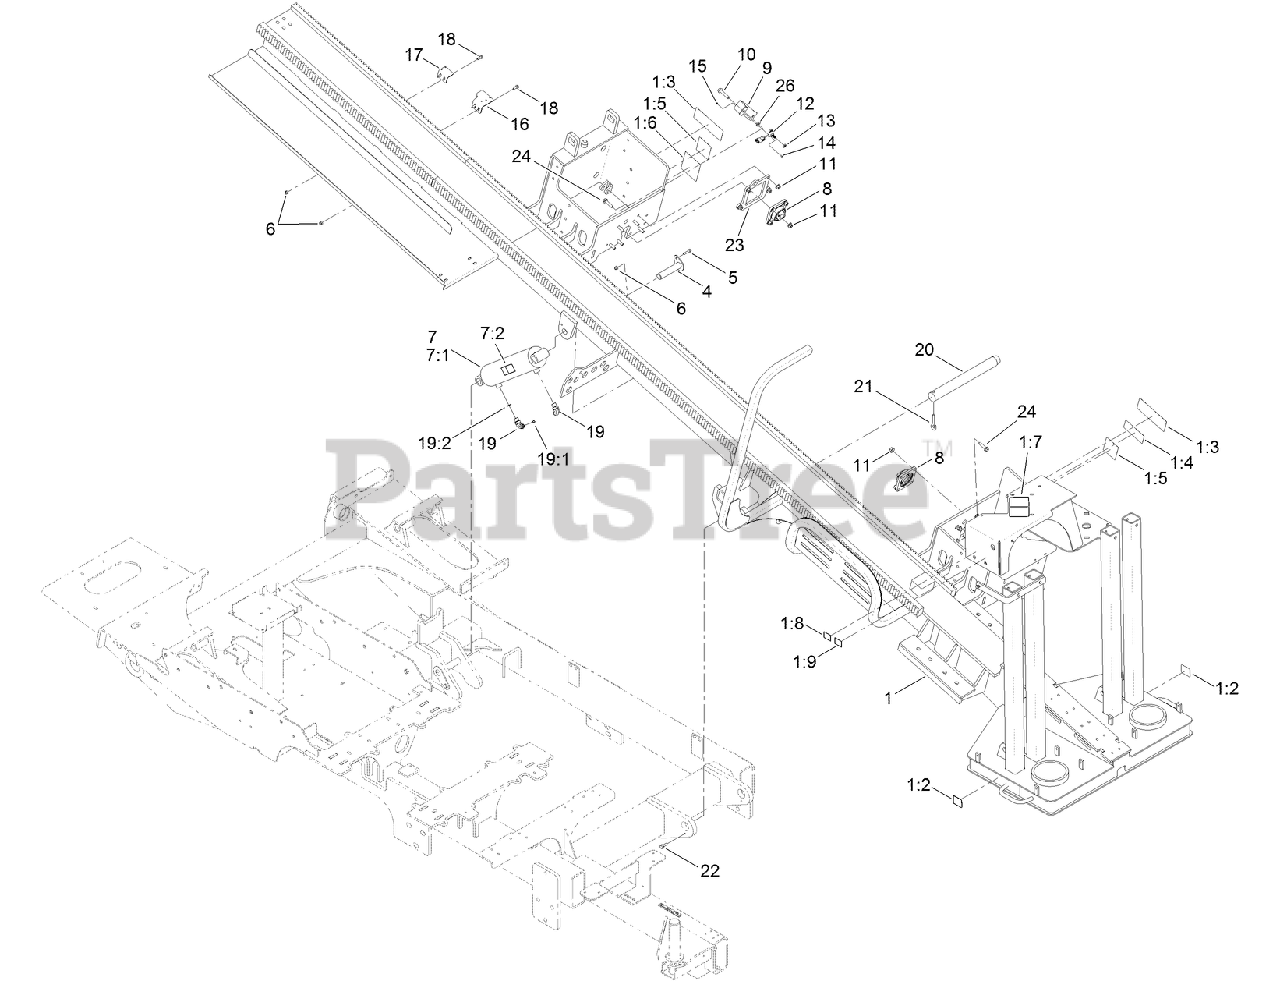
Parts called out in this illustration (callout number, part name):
1	THRUST FRAME ASM
1:2	DECAL-TIE DOWN
1:3	DECAL-DANGER, HAZARDOUS AREA
1:4	DECAL-WARNING, HYDRAULIC PRESSURE
1:5	DECAL-WARNING, CRUSHING
1:6	DECAL-SHOCK DANGER
1:7	DECAL-STAKEDOWN SET UP
1:8	DECAL-PIPE RETURN, CLEAR
1:9	DECAL-PIPE BREAKOUT, CLEAR
4	PIN-PIVOT
5	SCREW-HHF
6	NUT-LOCK, HHF
7	LIFT CYLINDER ASM
7:1	HYD CYLINDER ASM
7:2	DECAL-CAUTION, CYLINDER LOCK
8	BEARING-FLANGED Y, SQUARE
9	PLATE-MOUNTING
10	SCREW-HHF
11	NUT-LOCK, HHF
12	SENSOR-ROTARY
13	NUT-HEX
15	NUT-HEX, KEPS
16	PLATE-MOUNT, PROXIMITY SWITCH
17	PLATE-MOUNT, SWITCH
18	SCREW-HHF
19	FITTING-ELBOW 90
19:1	O-RING
19:2	O-RING
20	PIN-PIVOT, MAIN
21	PIN-RETAINER
22	SCREW-HHF
23	PLATE-SUPPORT, BEARING
24	SCREW-HHF
26	WASHER-FLAT
